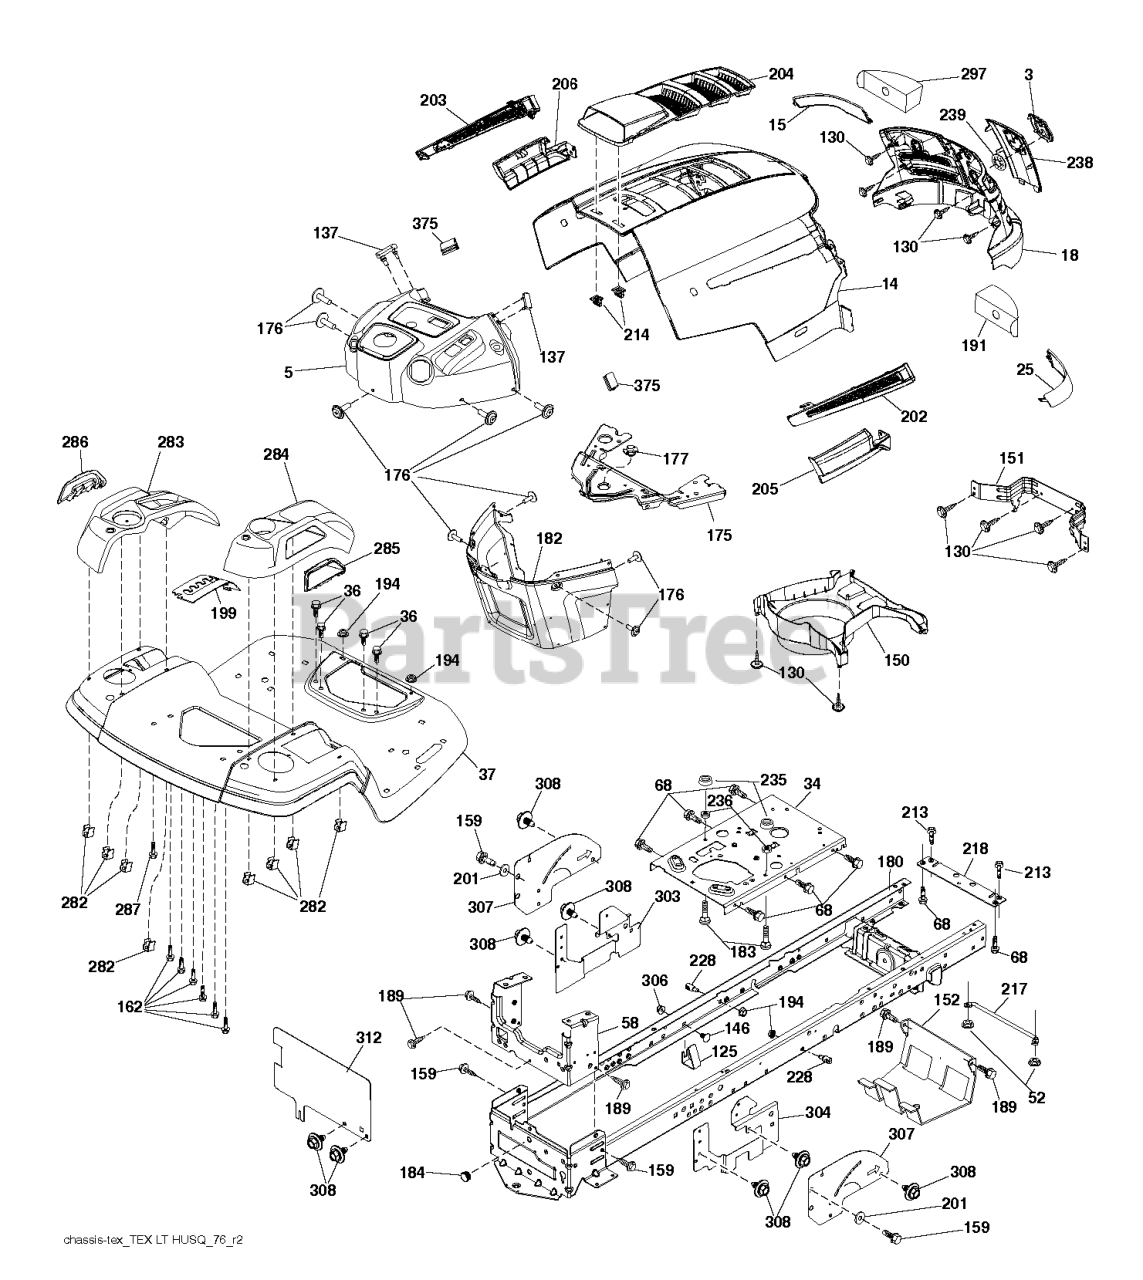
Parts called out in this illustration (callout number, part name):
3	LOGO.HUSQ.GT.LT.CROWN.H
5	DASH.HUSLT.PTO.RS.CHG.SRV.498
14	HOOD.HUSQVARNA.LT.ORANGE
15	LENS.HUSQVARNA LT.RH
18	GRILLE.SVC.HUSQVARNA.GREY
25	LENS.HUSQVARNA LT.RH
34	PLATE.ENGINE.WELDED.CHASSIS
36	SCREW 5/16"
37	FENDER.TLT.FS.W/CUPHLD.ORANGE
52	LOCKNUT
58	DRAWBAR UPPER 2PC SMALL FENDER
68	SCR 5/16-18 X 1/2 SELFTAP ZN
125	CLIP.FUEL.LINE
130	SCREW.#10 X 0.750.BOS
137	BUMPER DASH
146	BOLT.RDHD.SHT.SQNK.3/8-16X5/8
151	BRACKET PIVOT
152	SHIELD.BROWNING.W/TEX
159	SCREW, 3/8-16X3/4
162	SCREW.HI-LO.CONSOLE
175	CROSSMEMBER
176	SCREW.#10-24X5/8.RN.QU
177	BUSHING STEERING
180	CHASS.WLDMNT.TLT.12GA/2PC.20"
182	DASH.LOWER.PREDATOR LT
183	BOLT.5/16-18X1-1/4 FULL THD
184	PLUG.DEMO.625
189	SCREW
191	INSERT.REFLECTIVE.RH.
194	NUT LOCK HEX FLANGE 5/16-18
199	PLATE.DECK.LIFT.HUSQ.LT
201	WASHER
202	VENT.SIDE.HUSQVARNA.LT.RT
203	VENT.SIDE.HUSQVARNA.LT.LFT
204	SUBASM.TOP.VENT.HUSQ.LT
205	SKIRT.SIDE.HUSQVARNA.LT.RT
206	SKIRT.SIDE.HUSQVARNA.LT.LEFT
213	HCS 5/16C X 3/4
214	CLIP.RETAINER.TINNER.
217	ROD.PIVOT.HOOD
218	X-PIECE.HOOD.STOP.NON/
228	STUD.FASTNER.W/ANTI-ROTATE
235	SPACER FENDER
236	NUT.CENTERLOCK.5/16-
238	TRIM.HUSQ LT.668
282	CLIP.RETAINER.CONSOLE.LT.HUSQ
283	CONSOLE.ASM.LFT.RSF.HUSQ.LT
284	CONCOLE.CNTRL.PDL.HUSQ.LT.498
285	CONSOLE INSERT RH
286	CONSOLE.INSRT.LH.HUSQ.LT.BLACK
287	SCREW 1/4X20
297	INSERT REFLECTIVE
303	SHIELD.LWR.LH.LTGT.NON30
304	SHIELD.LWR.RH.LTGT.NON30.NOTCH
306	NUT LOCK FLG 3/8-16 UNC
307	SHIELD.UPPER.LT.GT.ISO
308	BOLT.5/16-18UNCX3/4 W/SEMS.BLK
312	COVER DRBAR.LT.FRTTANK.ISO X43
375	BUMPER CLIP-ON. DASH 1"
